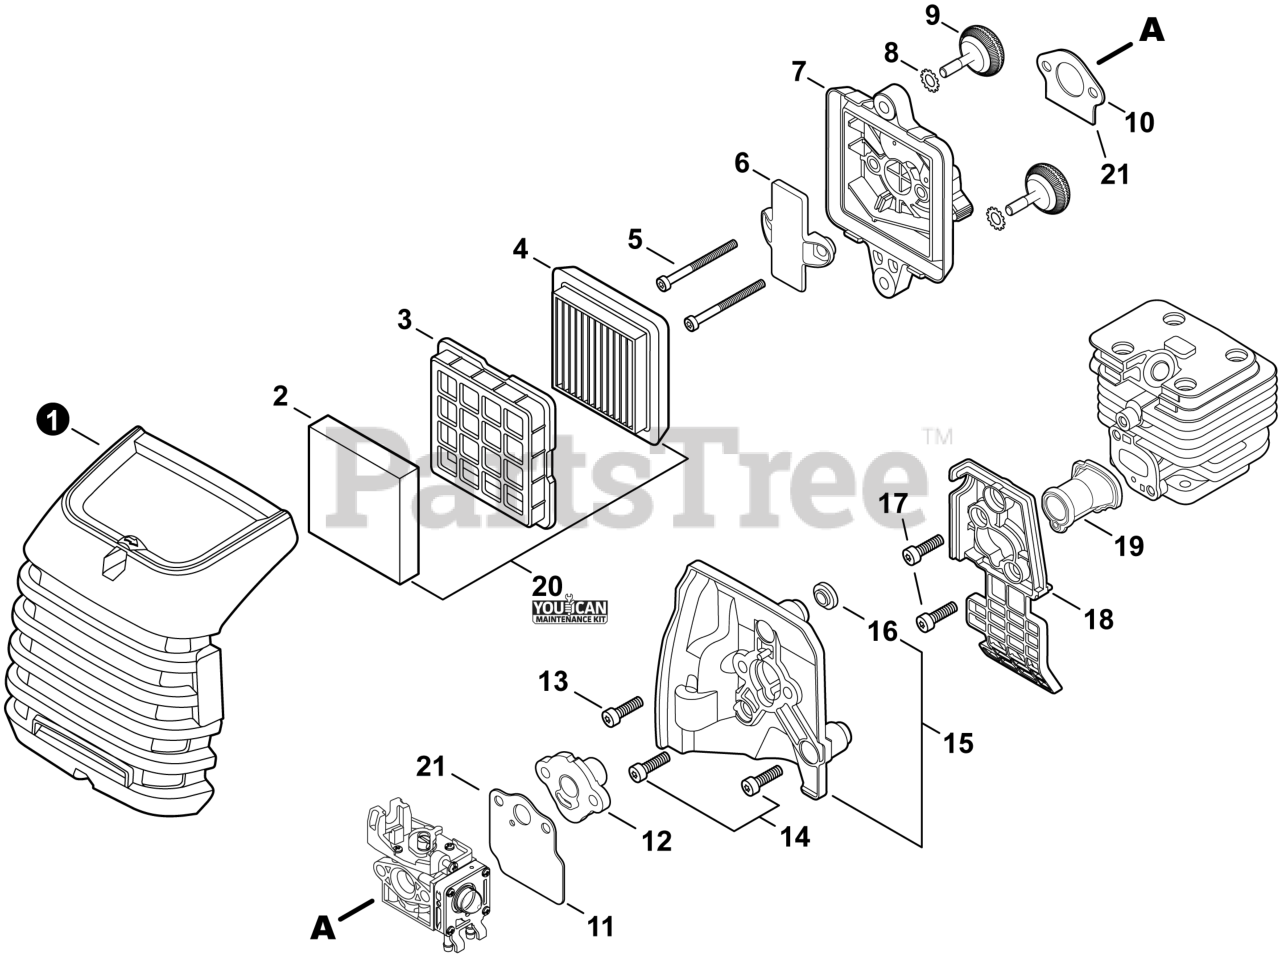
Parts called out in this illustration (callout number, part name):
1	COVER, AIR FILTER
2	PRE-FILTER, FOAM
3	RETAINER, PRE-FILTER
4	FILTER, AIR
5	BOLT, TORX 5×60
6	PLATE, PREVENT
7	CASE, AIR FILTER
8	WASHER, LOCK
9	THUMBSCREW
10	GASKET, INTAKE
11	HEAT SHIELD, INTAKE
12	BOOT, INSULATOR PLATE
13	BOLT, TORX 5×20
14	BOLT, TORX 5×16
15	PLATE, INSULATOR
16	COLLAR 5
17	SCREW 5×16
18	HOLDER, BELLOWS
19	BELLOWS, INTAKE
20	TUNE-UP KIT - YOUCANT
21	GASKET KIT: ENGINE, INTAKE, EXHAUST
